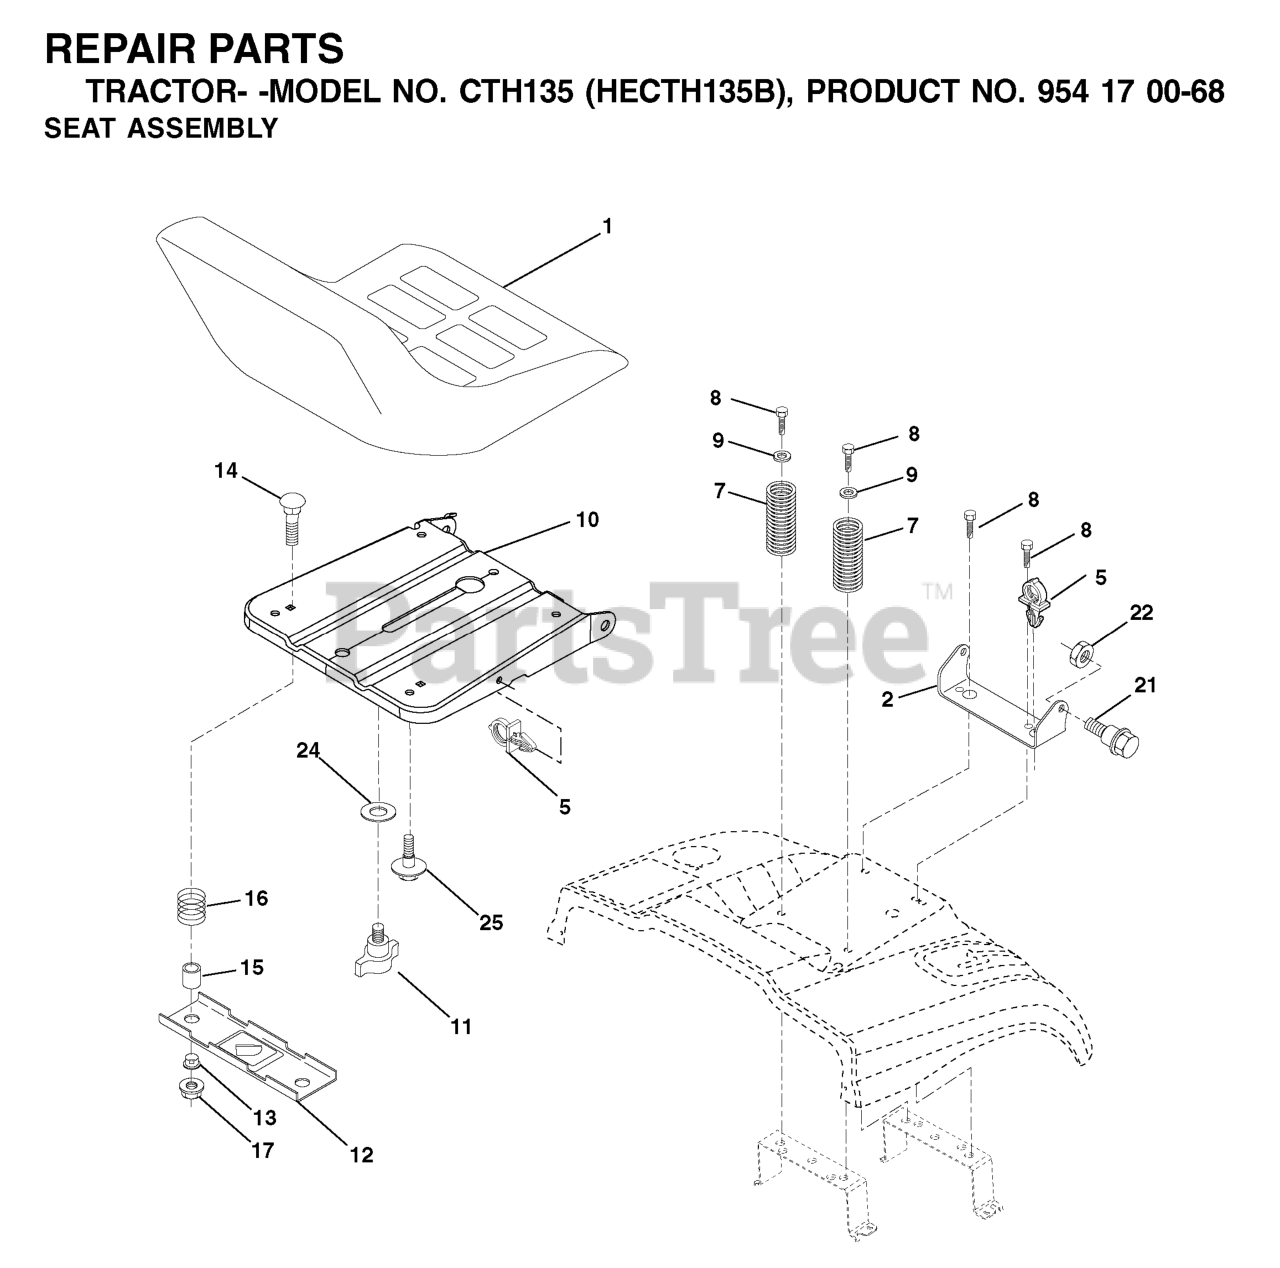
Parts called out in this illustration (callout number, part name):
1	SEAT, GRAY
2	SEAT PIVOT BRKT
7	SPRING COMPRESSION
8	SCREW 3/8-16X1
9	WASHER
10	PAN, SEAT
11	KNOB.SEAT.ADJ.WINGNUT
12	BRKT SWITCH
14	BOLT.ROUND.HEAD.SQUARE.NECK
15	SPACER SPLIT 28X.96
17	NUT T
21	BOLT.SHOULDER.5/16-18
22	NUT.71038.31-18.HEX.NYLOCK
25	BOLT,SHOULD
